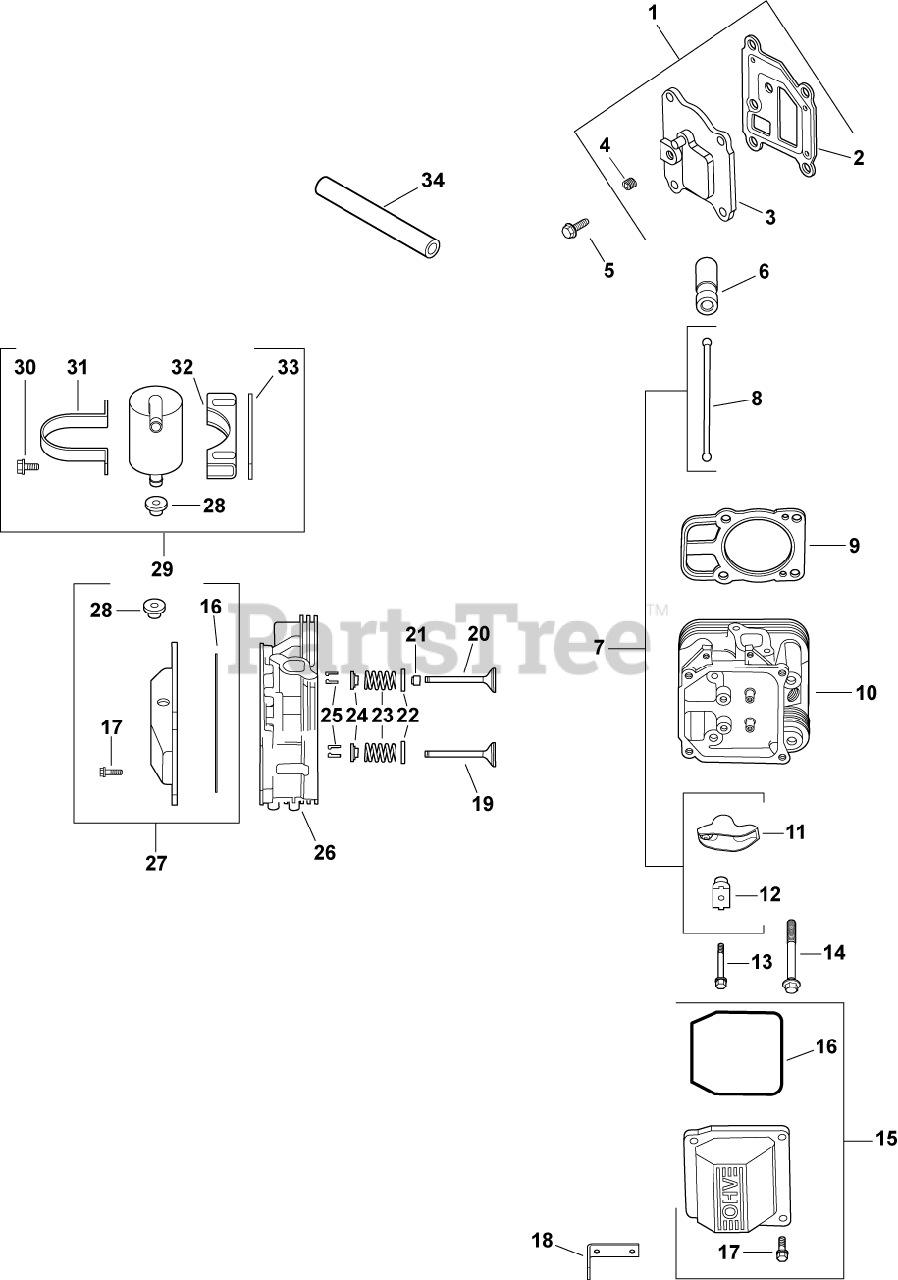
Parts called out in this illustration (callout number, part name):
1	KIT, BREATHER COVER W/GASKET
2	GASKET, BREATHER-USE 24 041 67-S
3	COVER, BREATHER -USE 24 096 125-S
4	PLUG, CTSK PIPE 1/8"
5	SCREW,FLG THD FRM M6X1.0X20-(#25086396S)
6	LIFTER, HYDRAULIC VALVE-USE 25 351 10-S
7	KIT, VALVE TRAIN
8	ROD, PUSH
9	CYL HEAD GASKET KIT-USE 24 841 04-S
10	KIT, CYLINDER HEAD #2
11	ARM, ROCKER
12	PIVOT, ROCKER ARM
13	SCREW - USE 62 086 08-S
14	SCREW, FLG M6X1.0X34
15	KIT, VALVE COVER-PLAIN
16	O-RING (YELLOW), VALVE COVER
17	SCREW, FLG M6X1.0X30
18	STRAP, LIFTING-USE 25 445 03-S
19	VALVE, EXHAUST (STD) - USE 32 016 01-S
20	VALVE, INTAKE (STD)
21	SEAL, VALVE STEM - (#2503214S)
22	RETAINER, SPRING
23	SPRING, VALVE
24	RETAINER, VALVE SPRING - USE 25 173 28-S
25	KIT, RETAINER
26	KIT, CYLINDER HEAD #1
27	KIT, VALVE COVER
28	GROMMET, RUBBER
29	KIT, BREATHR SEPARATR-(#24755241S)
30	SCREW,FLG THD FRM M5X0.8X16-(#25086398S)
31	STRAP, BREATHER - USE 24 755 241-S
32	BRACKET, BREATHER SEPARATOR
33	SPACER
34	HOSE, BREATHER-USE 24 326 63-S
2401602-S	VALVE, EXHAUST (.25)
2401702-S	VALVE, INTAKE (.25)
